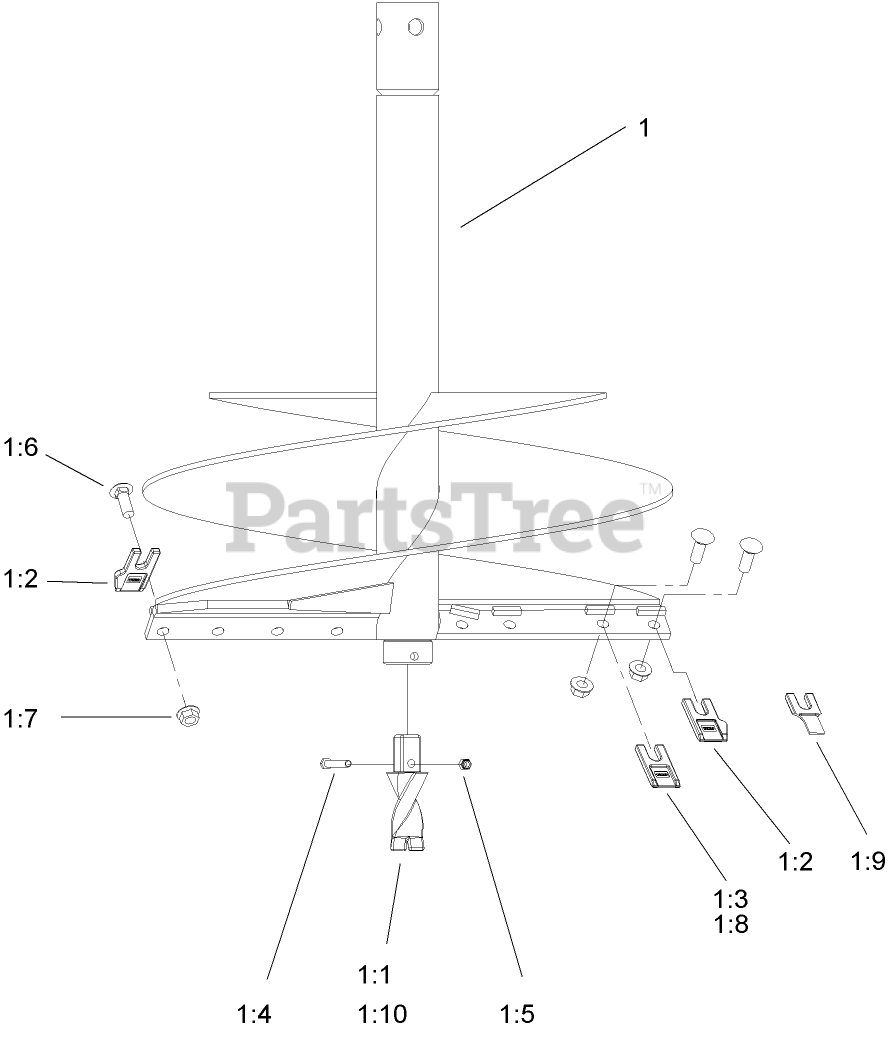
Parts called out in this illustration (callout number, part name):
1	AUGER-24 Inch
1:1	FISHTAIL-SHANK, SQUARE
1:2	TOOTH-AUGER, GAGE
1:3	TOOTH-AUGER, WISDOM
1:4	SCREW-HH
1:5	NUT-LOCK, NI
1:6	SCREW-CARR
1:7	NUT-LOCK, NI
1:8	TOOTH-WISDOM, CARBIDE
1:9	TOOTH-CHISEL, CARBIDE
1:10	PILOT-HARDFACED
